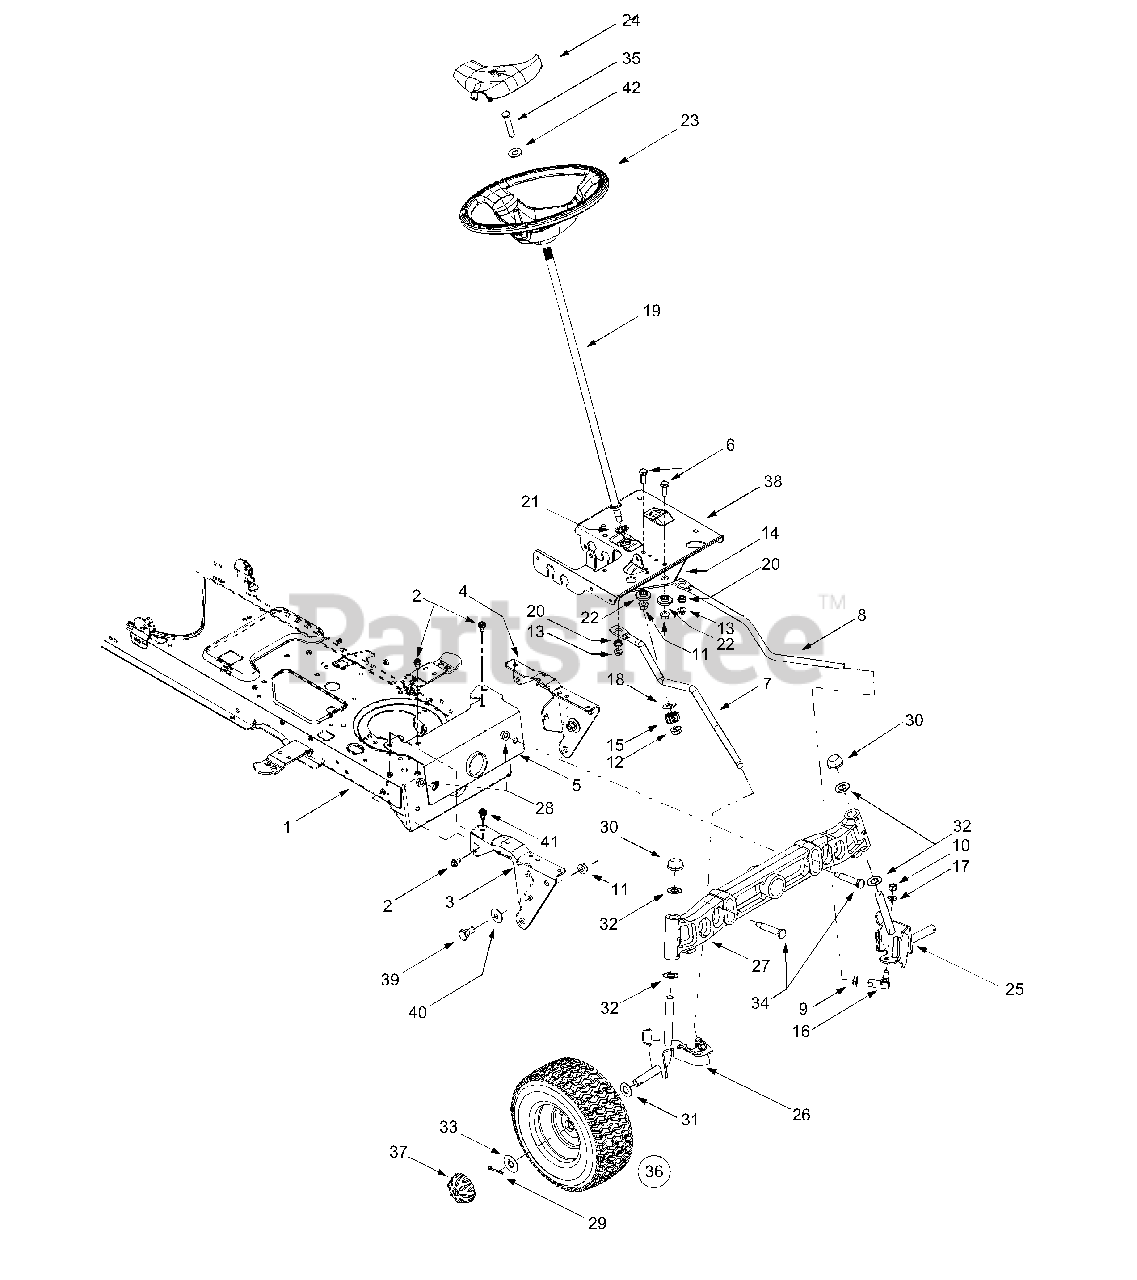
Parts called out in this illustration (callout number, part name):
6	Hex Cap Screw, 3/8-16 x 1 (Grade 5)
7	RH Drag Link
8	LH Drag Link
9	Jam Nut, 7/16-20 (Grade 2)
10	Hex Nut, 3/8-24 (Grade 2)
11	Flange Lock Nut, 3/8-16
12	Flange Lock Nut, 7/16-20
13	HEX FLANGE NUT
14	Steering Gear, 11/90 Ratio
15	Steering Pinion Gear
16	Ball Joint, 7/16-20
17	Lock Washer, 3/8
18	Flat Washer, .51 x 1.12 x .06
19	Steering Shaft, .625 OD x 24.4
20	Plastic Bushing, .38 ID
21	Hex Flange Bearing, 5/8
22	Shoulder Spacer, .38 ID
23	Soft Touch Steering Wheel
24	Steering Wheel Cap
25	LH Axle Assembly, .625 Dia.
25	LH Axle Assembly, .625/.750 Dia.
26	RH Axle Assembly, .625 Dia.
26	RH Axle Assembly, .625/.750 Dia.
27	Cast Iron Pivot Bar w/ Fittings, .625
27	Cast Iron Pivot Bar w/ Fittings, .750
28	Flange Lock Nut, 3/8-16
29	Cotter Pin
30	Push Cap, .625
31	Flat Washer, .64 x 1.0 x .12
32	Flat Washer, .64 x 1.24 x .06
32	Flat Washer, .78 x 1.59 x .06
33	Flat Washer, .635 x 1.589 x .06
34	Shoulder Screw, .5 x 2.2, 3/8-16
35	Hex Bolt, 5/16-18 X 1
37	Hub Cap
38	Steering Support Bracket
39	SHOULDER SCREW .498 DIA x .340
40	Bell Washer, .39 x 1.13 x .062
41	Self-tapping Screw, 5/16-18 x .75
42	Bell Washer, .34 x .872
